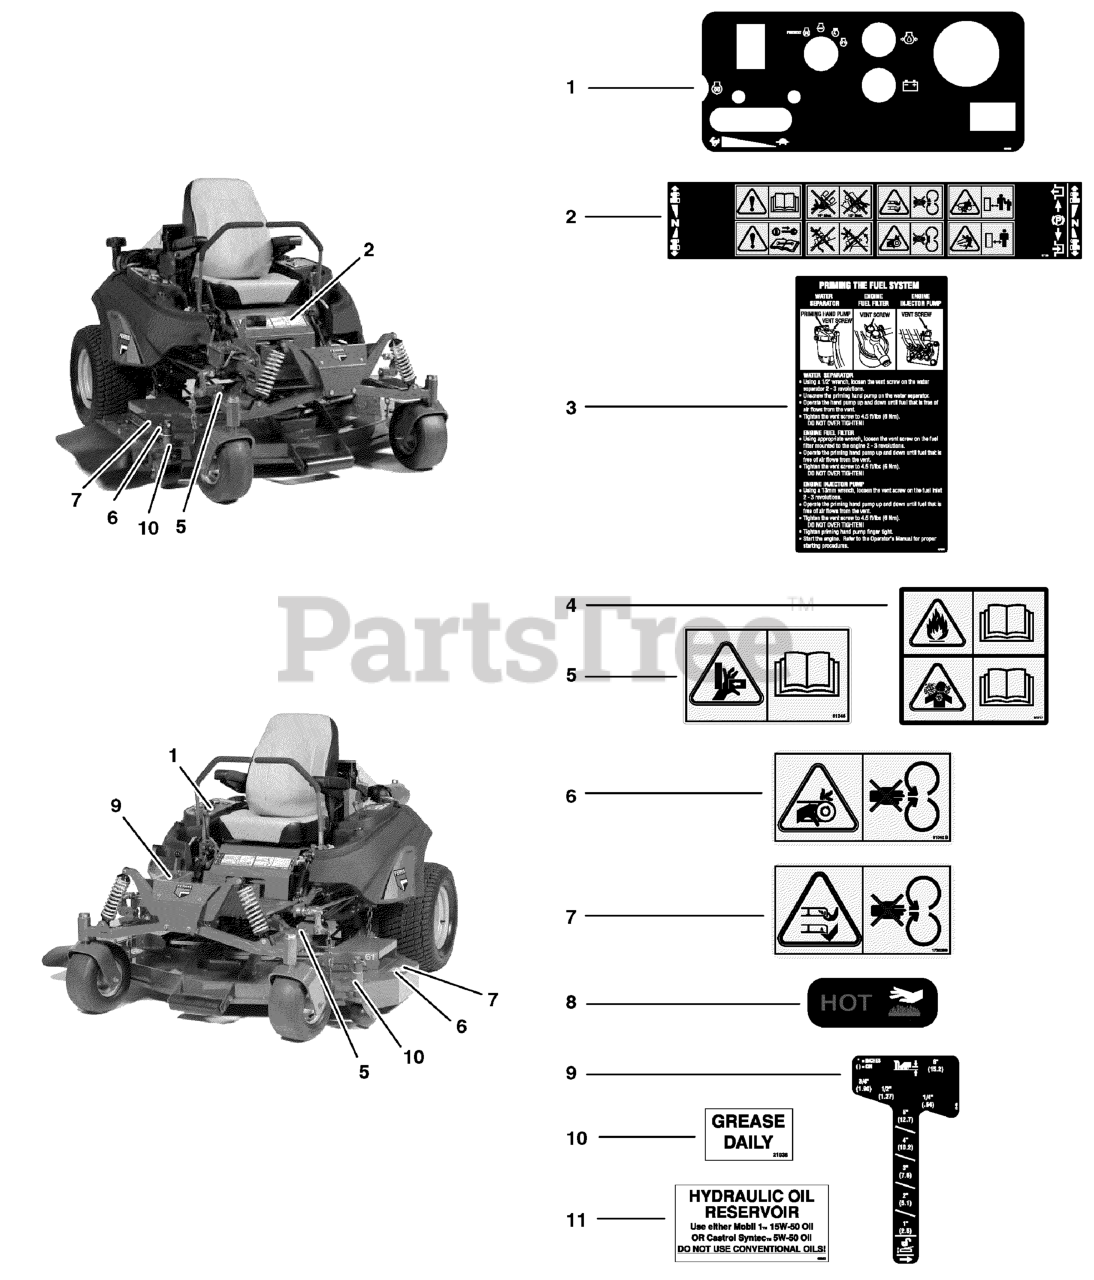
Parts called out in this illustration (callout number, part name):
1	DECAL, Control Panel, Diesel
2	DECAL, Main, CE
3	DECAL, Priming Instructions
4	DECAL, Danger, Open Flame
5	DECAL, Pinch Point, CE
6	DECAL, Warning, Hand In Belt
7	DECAL, Warning, Mower
8	DECAL, Hot Surface
9	DECAL, Height of Cut
10	DECAL, Grease Daily
11	DECAL, Oil Reservoir
